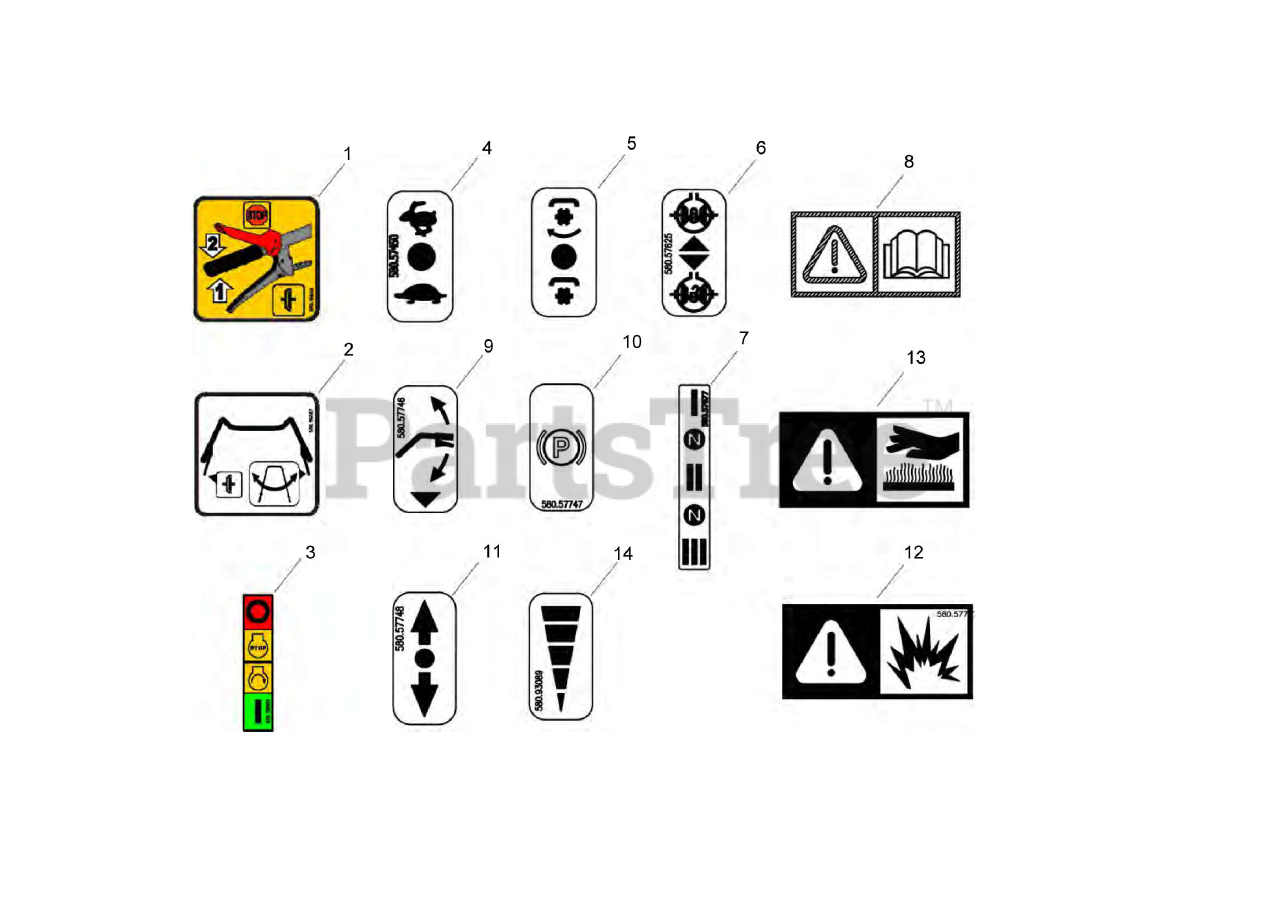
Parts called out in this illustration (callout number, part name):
1	DECAL, CLUTCH/OPERATOR PRESENCE LEVER
2	DECAL, HANDLE BAR SWIVEL
3	DECAL, KILL SWITCH
4	DECAL, THROTTLE
5	DECAL, PTO ENGAGEMENT
6	DECAL, DIFFERENTIAL LOCK
7	DECAL, GEAR SELECT
8	DECAL, READ MANUAL
9	DECAL, HANDLE BAR UP/DOWN
10	DECAL, PARKING BRAKE
11	DECAL, FORWARD/REVERSE
12	DECAL, FUEL SPARK DANGER
13	DECAL, CAUTION HOT
14	DECAL, SPEED CONTROL
